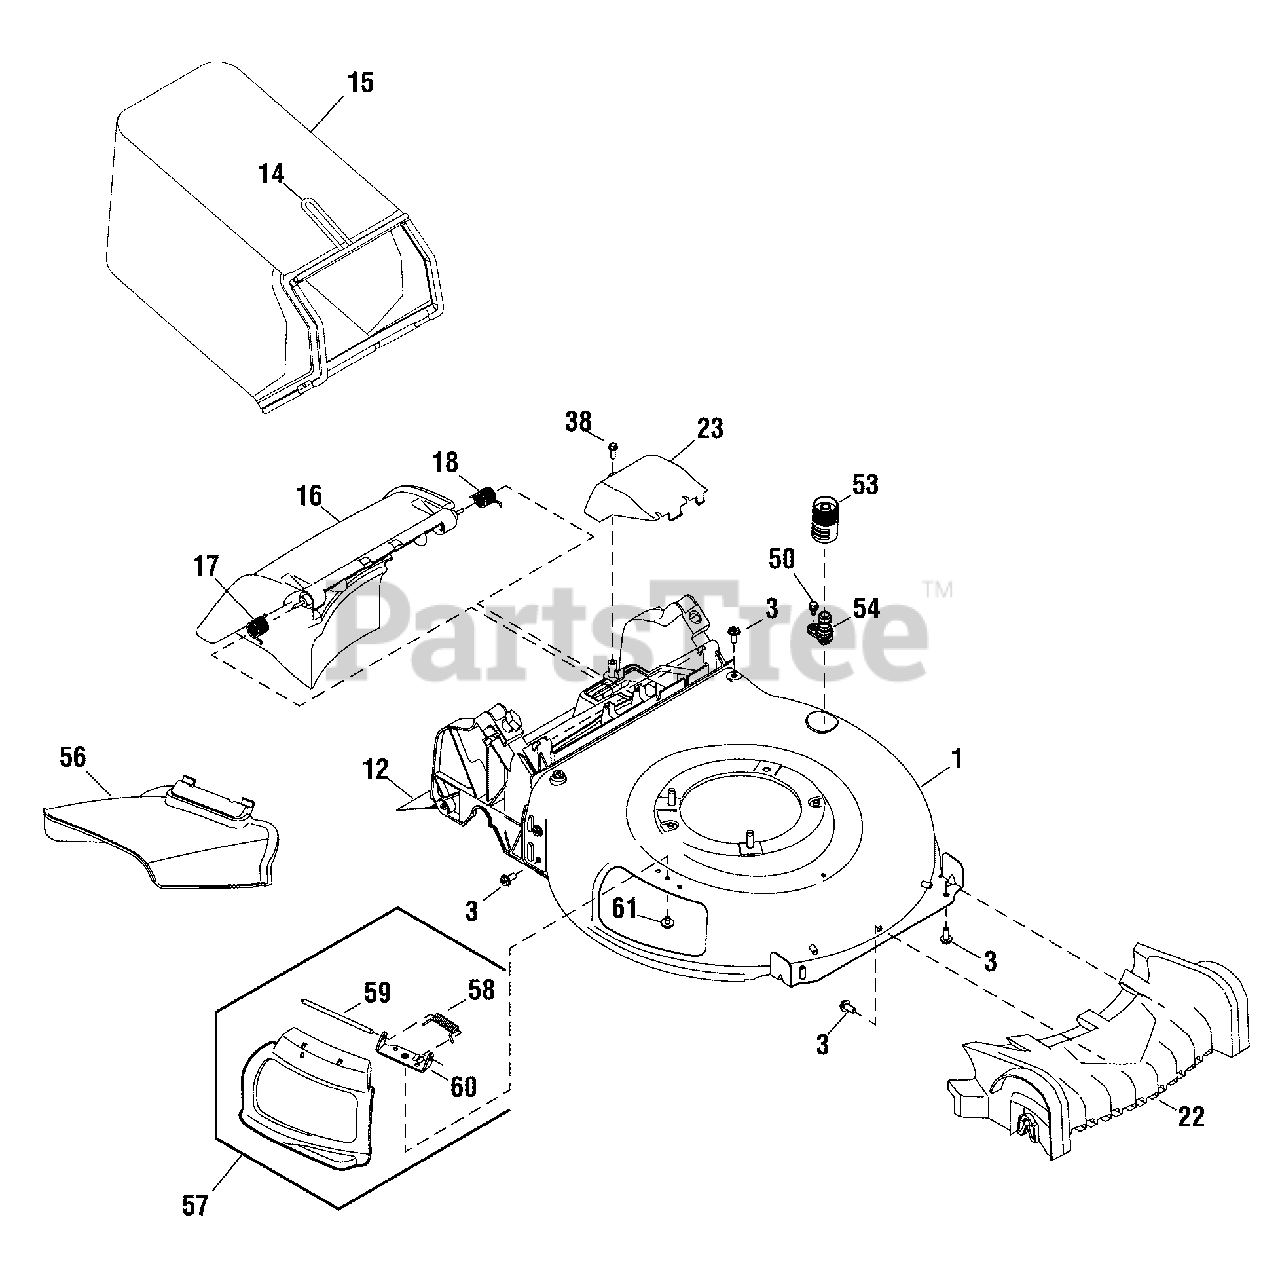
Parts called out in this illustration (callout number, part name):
1	DECK, 21"
3	SCREW, 5/16-14 x 3/4
12	SHIELD, Trailing
14	FRAME, Grass Bag
15	BAG, Grass
16	DOOR, Rear Discharge
17	SPRING, Torsion, RH
18	SPRING, Torsion, LH
22	COVER, Front
23	COVER, Transmission
38	SCREW, 1/4-15X3/4, Self-Tapping, BZ
50	BOLT, Shoulder, 1/4-20
53	ADAPTER, Water Nozzle
54	NOZZLE, Water
56	CHUTE, Side Discharge
57	MULCH PLUG
58	SPRING, Torsion
59	PIN, Hinge
60	BRACKET, Chute Deflector
61	SCREW, 1/4-20 x 1/2
